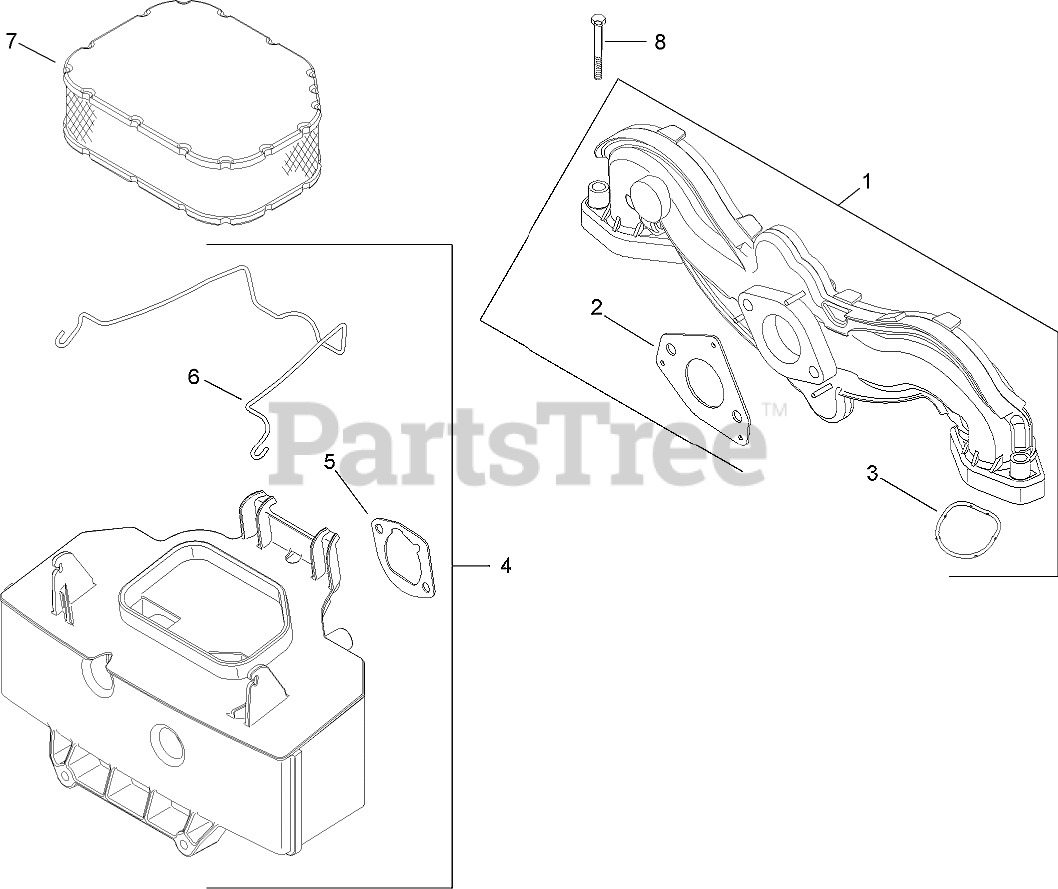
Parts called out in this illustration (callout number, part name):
1	Manifold-Intake (Includes2-3)
2	Gasket-Carburetor
3	O Ring-Intake Port
4	Base-Air Cleaner (Includes5-6)
5	Gasket-Air Cleaner Base
6	Latch-Air Cleaner Element
7	Element-Air Cleaner
8	Screw-Hex Flange (M6x1.0x40)
